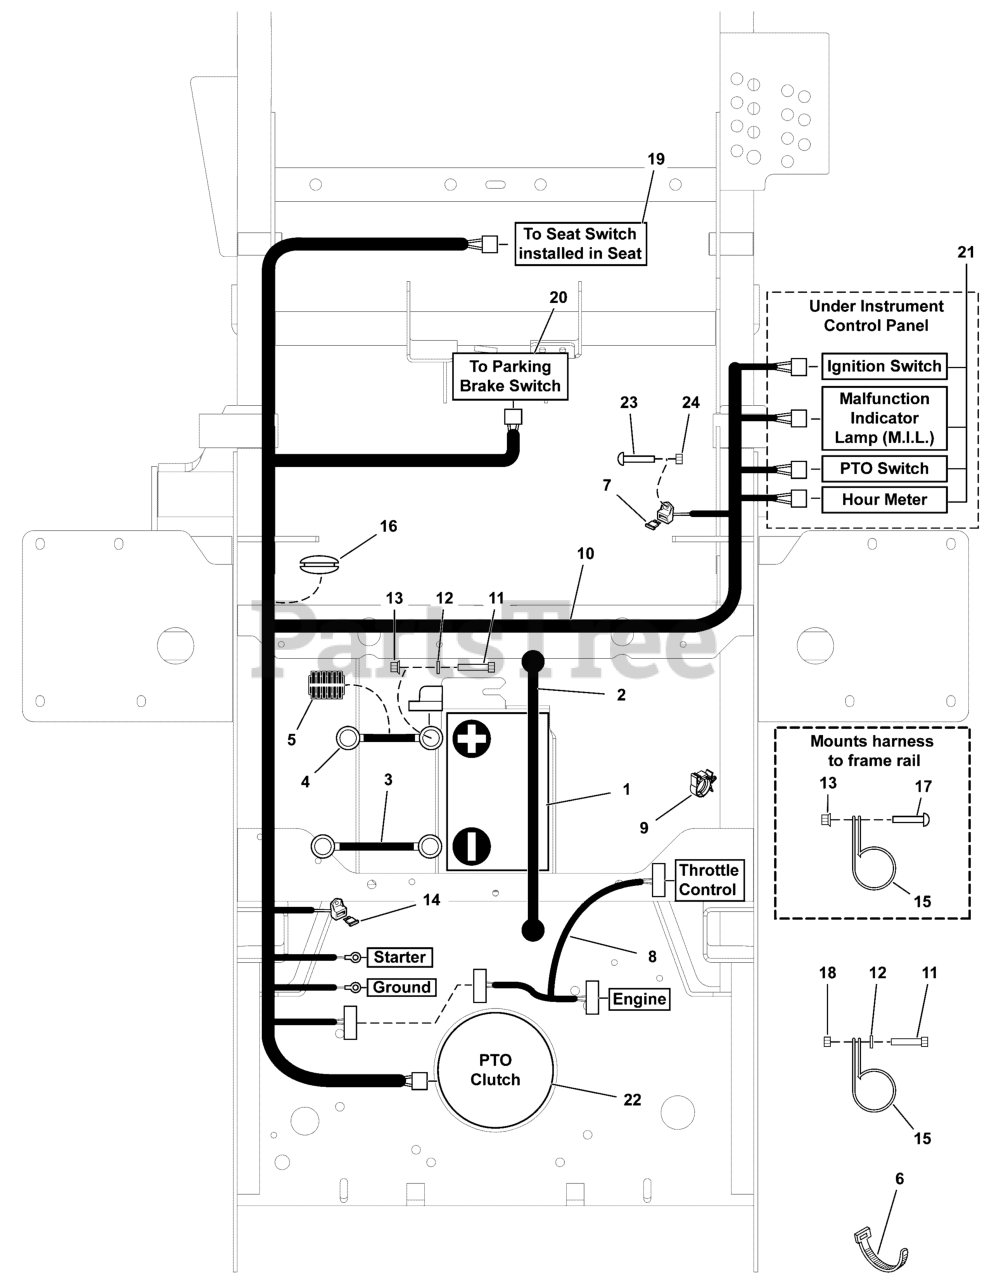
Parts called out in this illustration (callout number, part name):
2	STRAP, BATTERY, 14 LONG, Rubber
3	BATTERY CABLE, NEG, 22, 1/4-5/16
4	BATTERY CABLE, POS, 22, 1/4-5/16
5	WIRE LOOM, 3/8 ID X 16 IN
6	TIE, SELF-LOCKING, 12"
7	FUSE, ATO, 25 AMP
8	HARNESS, THROTTLE JUMPER, BRIGGS EFI
9	ROSEBUD LOOM CLIP
10	HARNESS, Wiring, Large ZTR
11	BOLT, 1/4"-20 X 3/4" GD5 YZ
12	WASHER, 1/4 SAE
13	NUT, 1/4-20 HEX SERR. FLANGE
14	FUSE, ATO-15 (15 AMP)(SV)
15	CLAMP, VINYL INSULATED, 1.00
16	GROMMET, 1-1/2" ID FOR 1/4" METAL
17	SCREW, 1/4-20 X 1, ALLEN BH, CZ
18	NUT, 1/4-20 Hex Nylock Flange
19	Refer to: Seat Mount & Floor Group
20	Refer to: Parking Brake Group
21	Refer to: Instrument Control Panel Group
22	Refer to: Engine & PTO Group
23	SCREW, #10-24 X 1/2" ROUND PHILLIPS
24	NUT, Hex, Nylon Lock, #10-24
